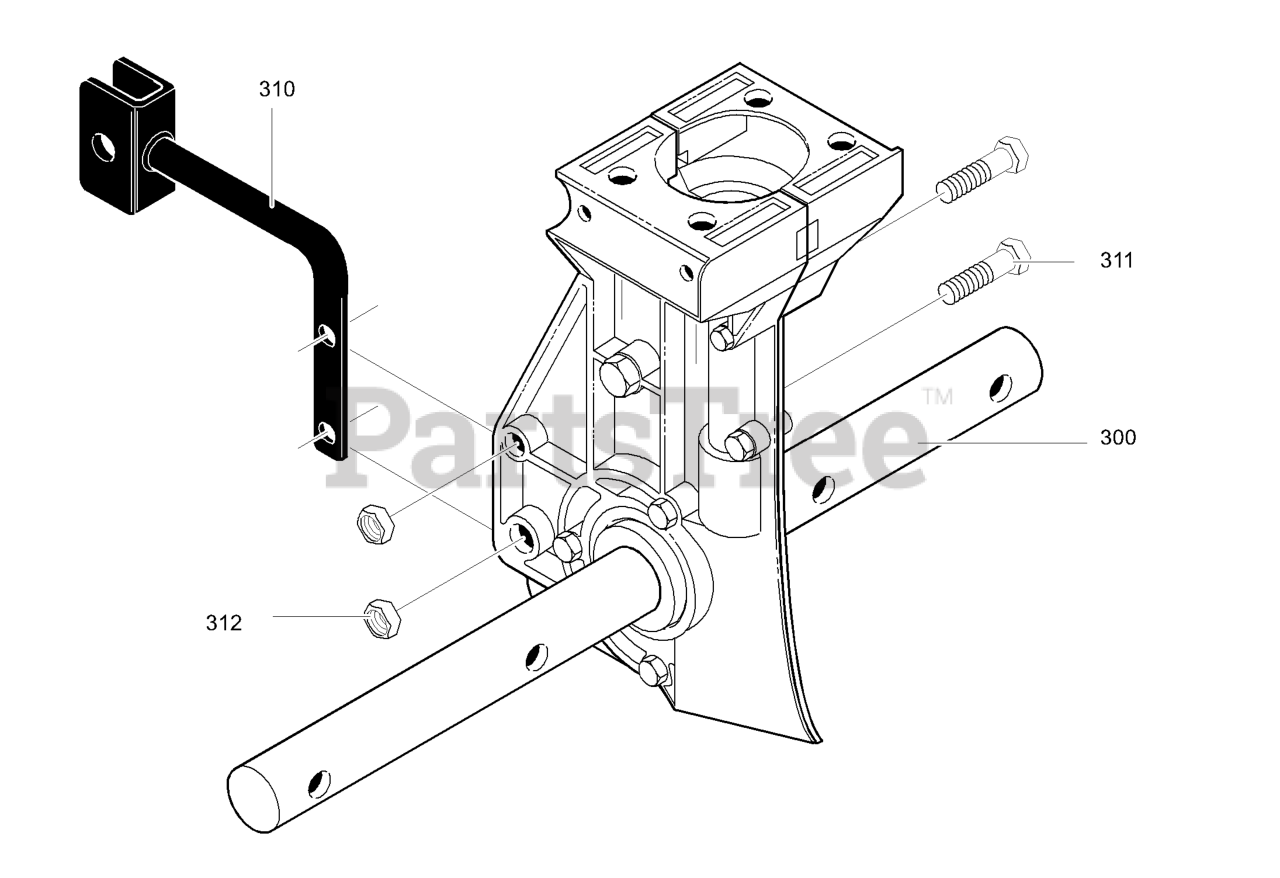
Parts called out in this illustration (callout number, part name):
300	Transmission
310	Bracket, Depth Rod
311	Screw, 1/4-20x1.25
312	Nut, 1/4-20
